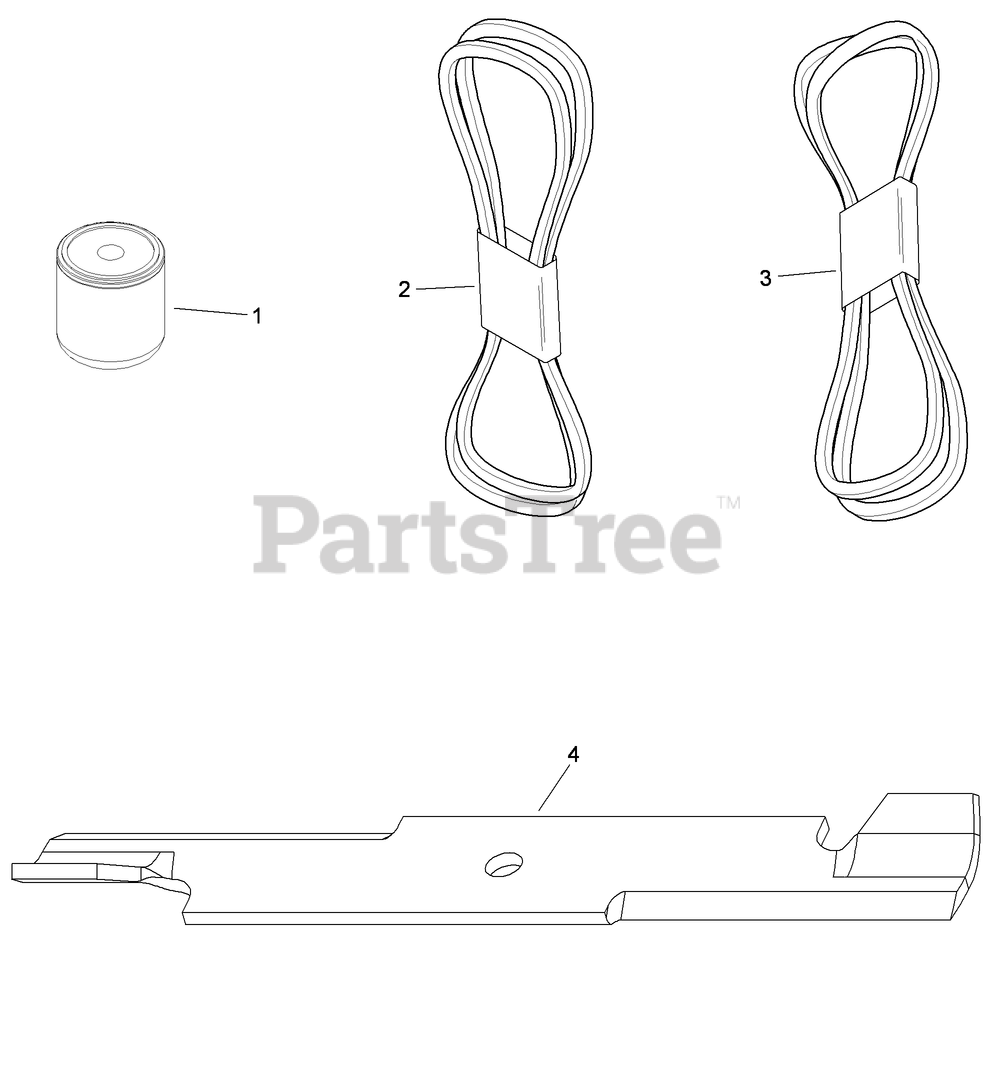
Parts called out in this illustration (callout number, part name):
1	FILTER-OIL, HYD
2	BELT-V
3	BELT-COG
4	BLADE-16.5 INCH (HIGH FLOW)
